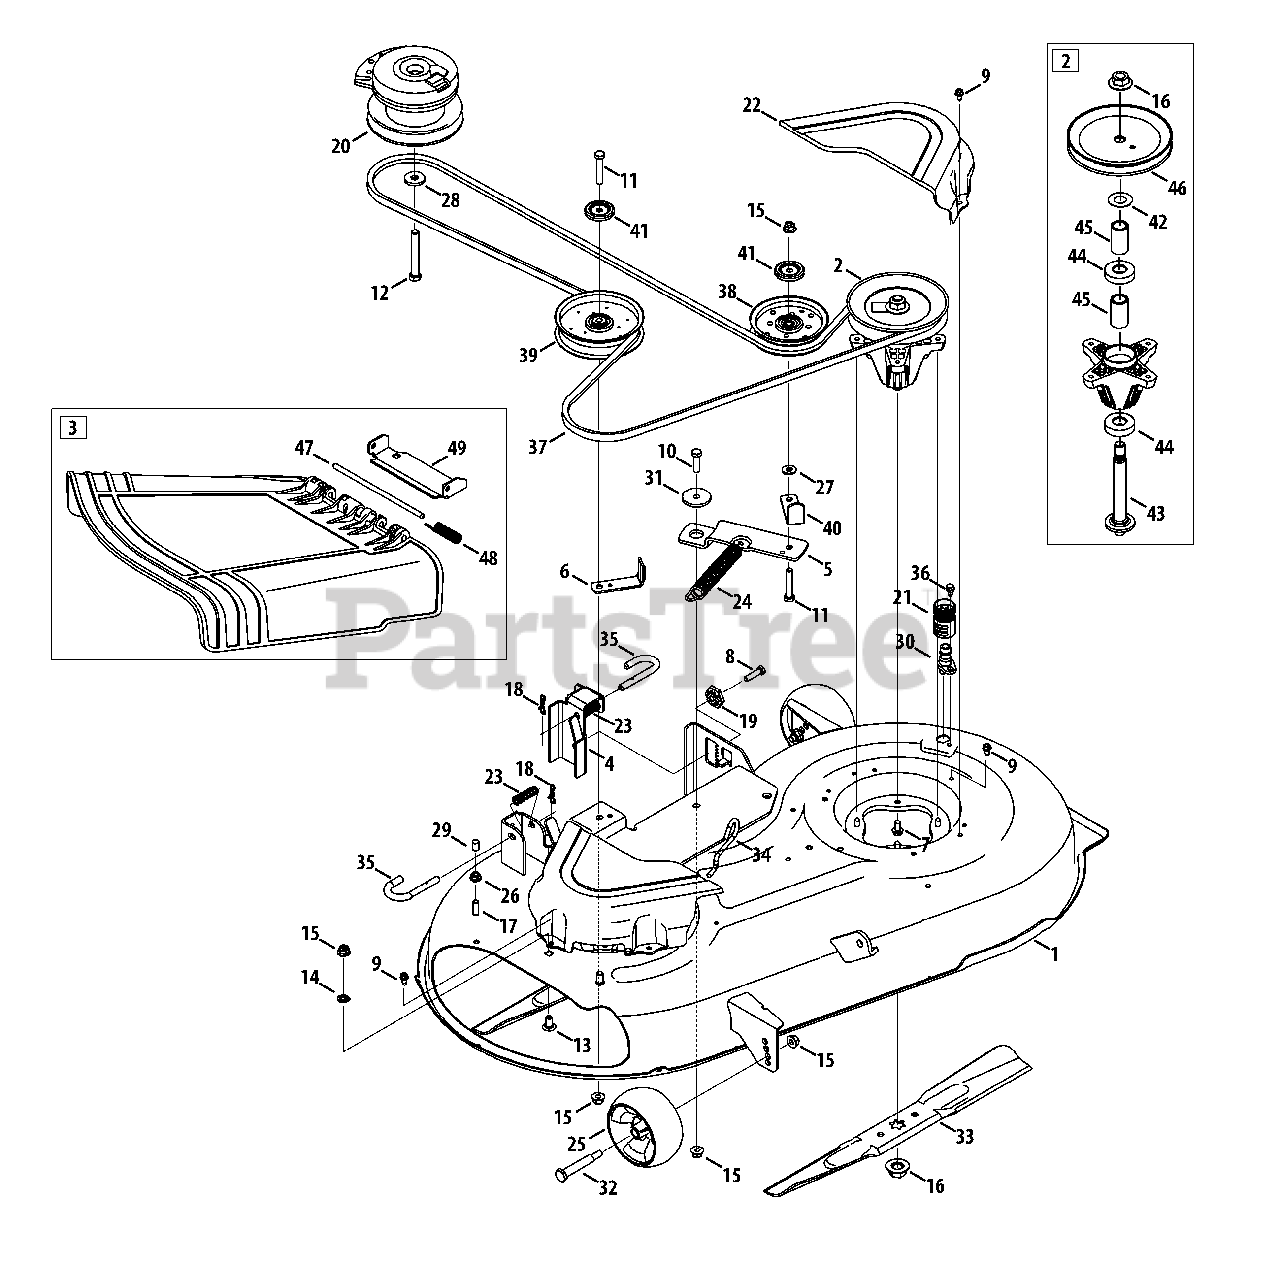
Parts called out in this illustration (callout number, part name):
1	42" Deck
2	Spindle Assembly
3	Discharge Chute Assembly
4	Deck Lift Bracket
5	Pivot Idler Bracket
6	Bracket, Belt Guard
7	Hex Washer Head Screw, 5/16-18 x .750
8	Hex Cap Screw, 5/16-18 x 1.25
9	Hex Washer Screw, 1/4-20 x .625
10	Hex Cap Screw, 3/8-16 x 1.25
11	Hex Cap Screw, 3/8-16 x 2.00
12	Screw, 7/16-20 x 3.25
13	Carriage Screw, 3/8-16 x .75
14	Push Nut, 3/8
15	Flange Lock Nut, 3/8-16
16	Hex Flange Nut, 5/8-18
17	Hex Cap Screw, 5/16-18 x 1.00
18	Bow-Tie Cotter Pin, 72
19	Deck Adjustment Gear
20	Electric PTO Clutch
21	Water Nozzle Adapter
22	Belt Cover
23	Compression Spring, .535 x 1.751
24	Extension Spring, .94 Dia. x 7.57
25	Deck Ball Wheel, 5.0
26	Flange Lock Nut, 5/16-18
27	Flat Washer, .385 x .870 x .092
28	Flat Washer, .450 x 1.25 x .164
29	Cap, .290 x .500
30	Deck Wash Nozzle
31	Shoulder Spacer, .884 x .190
32	Shoulder Screw, .5 x 2.5 x 3/8-16
33	Blade, 2 in 1, 21.23
34	Deck Spring Rod
35	Deck Hanger Rod
36	Shoulder Screw, .500 x 1/4-20
38	Idler Pulley, 4.25 Dia.
39	Idler Pulley, 5.00 Dia.
40	Bracket Belt Guard
41	Pulley Cap
42	Washer, .760 x 1.50 x .030
43	Spindle Shaft
44	Ball Bearing
45	Spacer, .792 x 1.060 x 1.860
46	Deck Pulley
48	Torsion Spring
49	Chute Bracket
